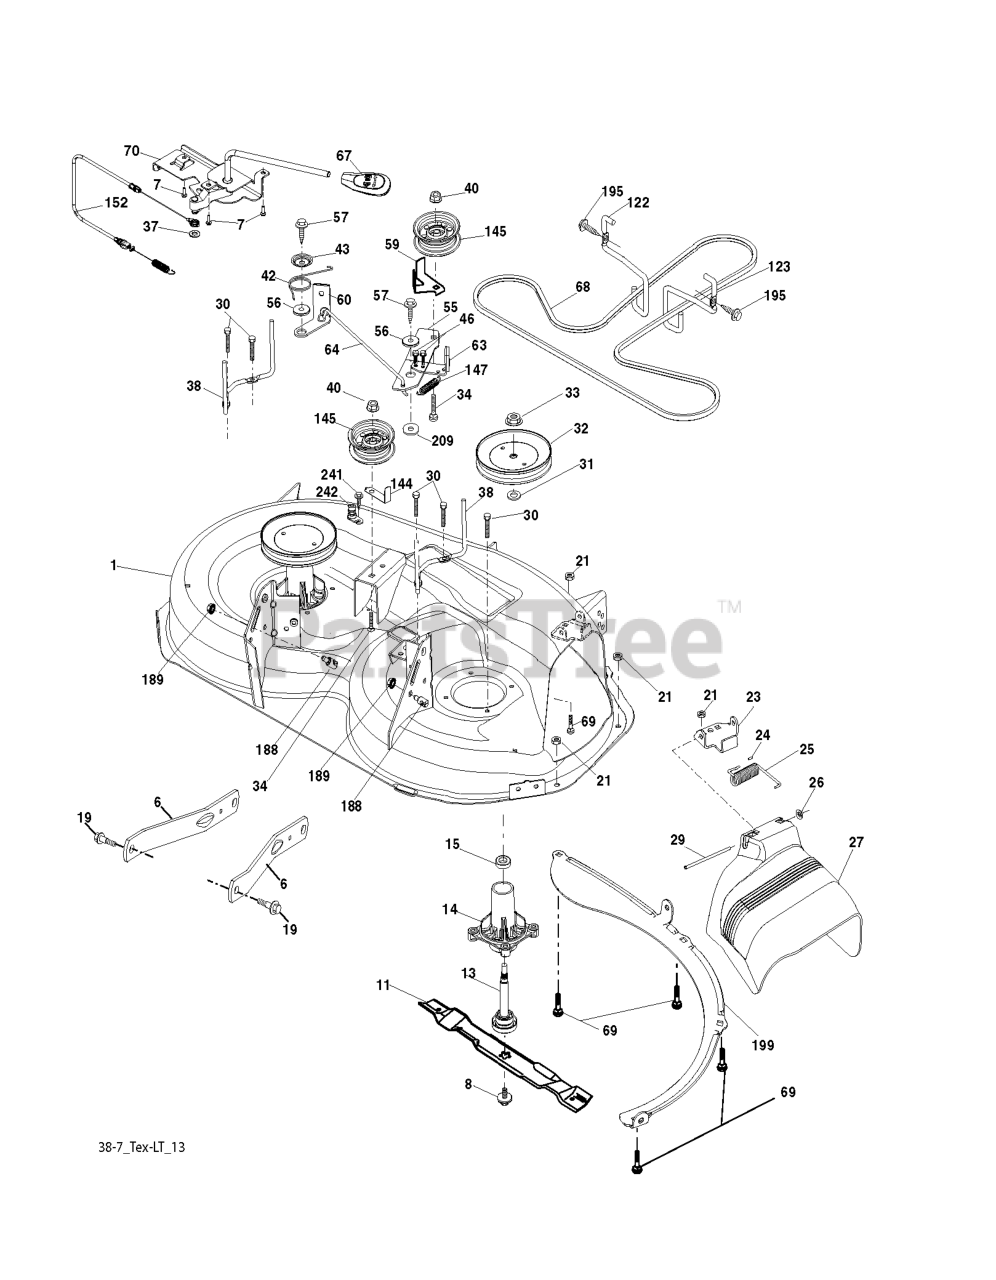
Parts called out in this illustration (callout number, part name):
1	HOUSING
6	ARM.SUSPENSION.MOWER.R
7	SCREW.#10 X 0.750.BOS
8	BOLT.WASHER.ASM.7/16-2
11	BLADE 38" PREMIUM
13	SHAFT.ASM.MDRL.N/GREASE.38
14	RP.HOUSING.MANDREL.4PT.
19	BOLT.SHOULDER
21	LOCKNUT
23	BRKT.DEFLECTOR.38"2005+
24	CAP-SLEEVE LT
25	SPRING.TORSION.DEFLECT
26	NUT PUSH M
27	SHIELD.DEFLECTOR.MWR.38-7/97CM
29	ROD.HINGE
30	SCREW, WASHER HEAD
31	WASHER.SPACER.MANDREL
32	PULLEY.MANDREL.5.0.PD.38"
33	NUT.FLANGE.LOCK.TOP
34	BOLT.3/8-16X1.50
37	WASHER
38	KEEPER BELT LH MANDREL
40	NUT LOCK FLG 3/8-16 UNC
42	SPRING.TORSION.BRAKE
43	SRPING.TORSION.RETAINE
46	SCREW.1/4-20X5/8
56	SPACER.RETAINER
57	SCREW 3/8-16X1
59	GUARD, BELT
60	ARM BRAKE MOWER RH 38"
63	RP ARM.BRAKE.MOWER.38"LH.TEX
64	LINK BRAKE
67	HANDLE.CLUTCH.CABLE.LT
69	BOLT
70	CLUTCH.ASM.MANUAL.LT.PRED
122	KEEPER BELT ENGINE LH
123	KEEPER BELT RH
144	KEEPER BELT
145	PULLEY.IDLER.48"PRIMARY
147	SPRING RETURN
152	CABLE.CLUTCH.MANUAL.
188	STUD.FASTNER.W/ANTI-ROTATE
189	NUT LOCK HEX FLANGE 5/16-18
195	SCREW, 3/8-16X3/4
199	BAFFLE.VORTEX.FRONT.38"
209	WASHER 12/32X2X10GA
241	SCREW.TT.#10-32X.5.3/8.FLANGE
242	PORT.WASHOUT
